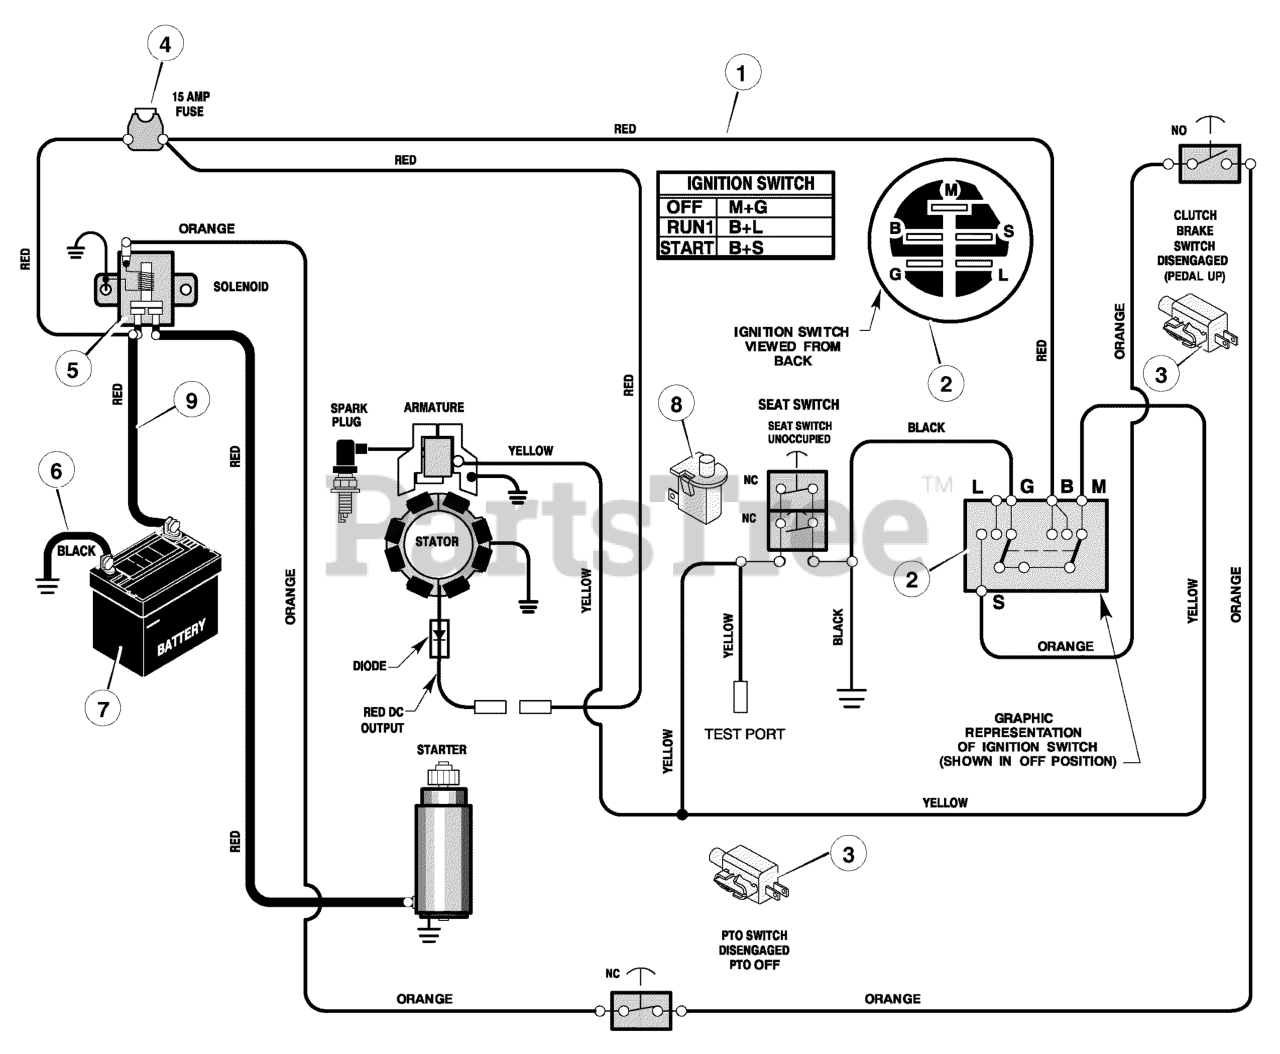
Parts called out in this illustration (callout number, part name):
4	WHEEL, 12 x 8-1/2, Front
5	VALVE STEM & CAP ASSEMBLY
5	Screw, Mounting
5	Locknut
6	WASHER, Special, 1 x 2-1/2
6	Cable, Battery Ground
7	WASHER
7	Battery
7	Bolt, Carriage
7	Wingnut
8	RING, Shaft
8	Switch, Seat Sensor
9	CAP, Hub Grey, 2-23/64
9	Cable, Red Batery
9	BOOT, Battery Terminal, Positive
10	KEY, HI PRO, 1/4 x 2
